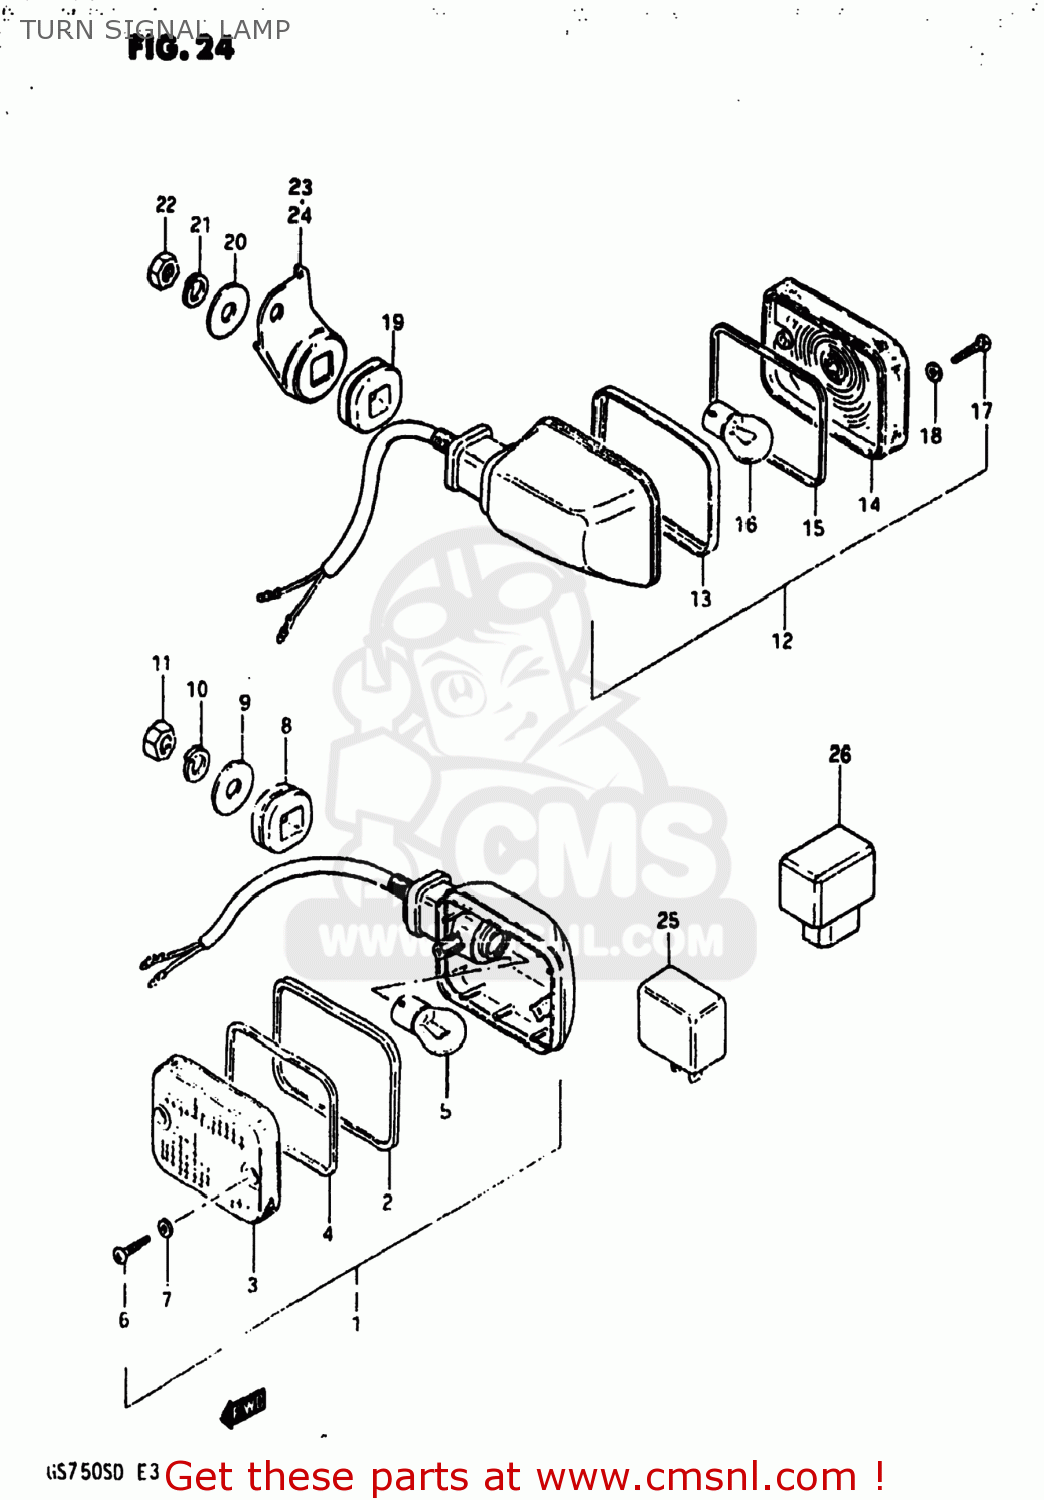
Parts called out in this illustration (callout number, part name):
1	LAMP ASSEMBLY,FRONT TURN SIGNAL
2	RIM
3	LENS
4	GASKET (NAS)
5	BULB(12V23W,STANLEY,A4577A)
6	SCREW
7	GASKET (NAS)
8	CUSHION
9	WASHER (10.5X30X2.3)
10	LOCK WASHER
11	NUT
12	LAMP ASSEMBLY,FRONT TURN SIGNAL
13	RIM
14	LENS
15	GASKET (NAS)
16	BULB(12V23W,STANLEY,A4577A)
17	SCREW
18	GASKET (NAS)
19	CUSHION
20	WASHER (10.5X30X2.3)
21	LOCK WASHER
22	NUT
23	BRACKET,RR TURNSIGNAL LAMP,R
24	BRACKET,RR TURNSIGNAL LAMP,L
25	RELAY ASSY,TURNSIGNAL
26	UNIT,TURN SIGNAL CONTROL
